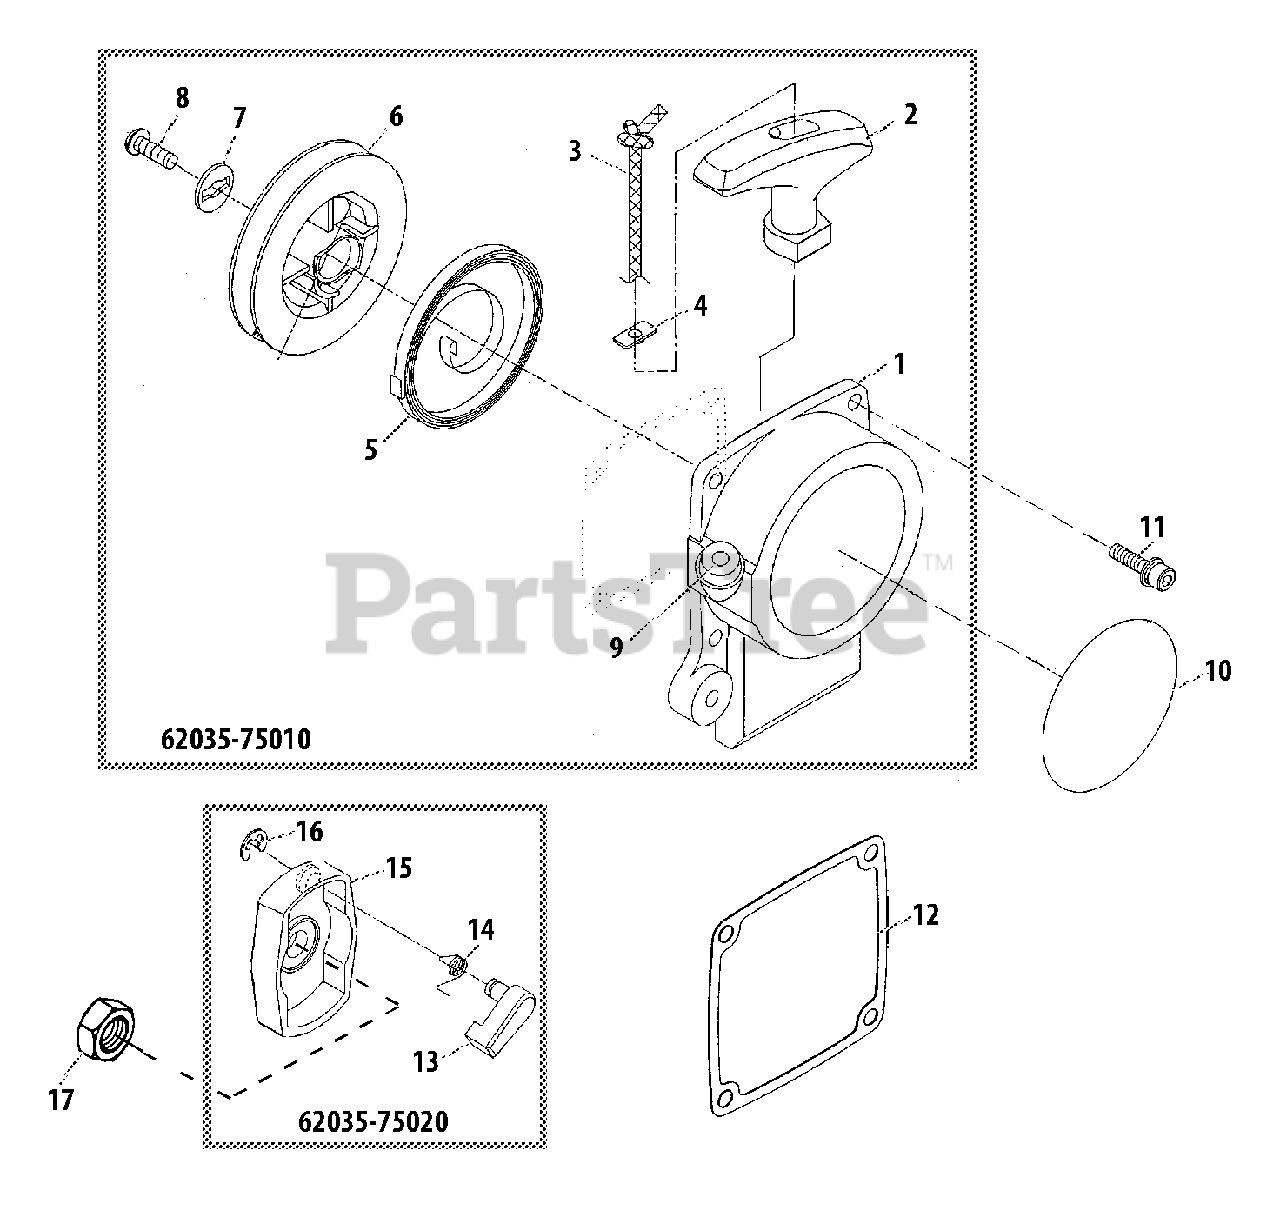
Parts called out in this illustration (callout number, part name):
1	CASE, STARTER
2	GRIP, STARTER
3	ROPE
4	RETAINER, ROPE
5	SPRING, REWIND
6	REEL, ROPE
7	WASHER
8	SCREW
9	GUIDE, ROPE
10	LABEL - MODEL
11	SCREW - 5X25
12	GASKET
13	RATCHET
14	SPRING, RETURN
15	REEL, ROPE
16	RING, RETAINING
17	NUT
62035-75010	STARTER ASSY
62035-75020	STARTER PAWL ASSY
